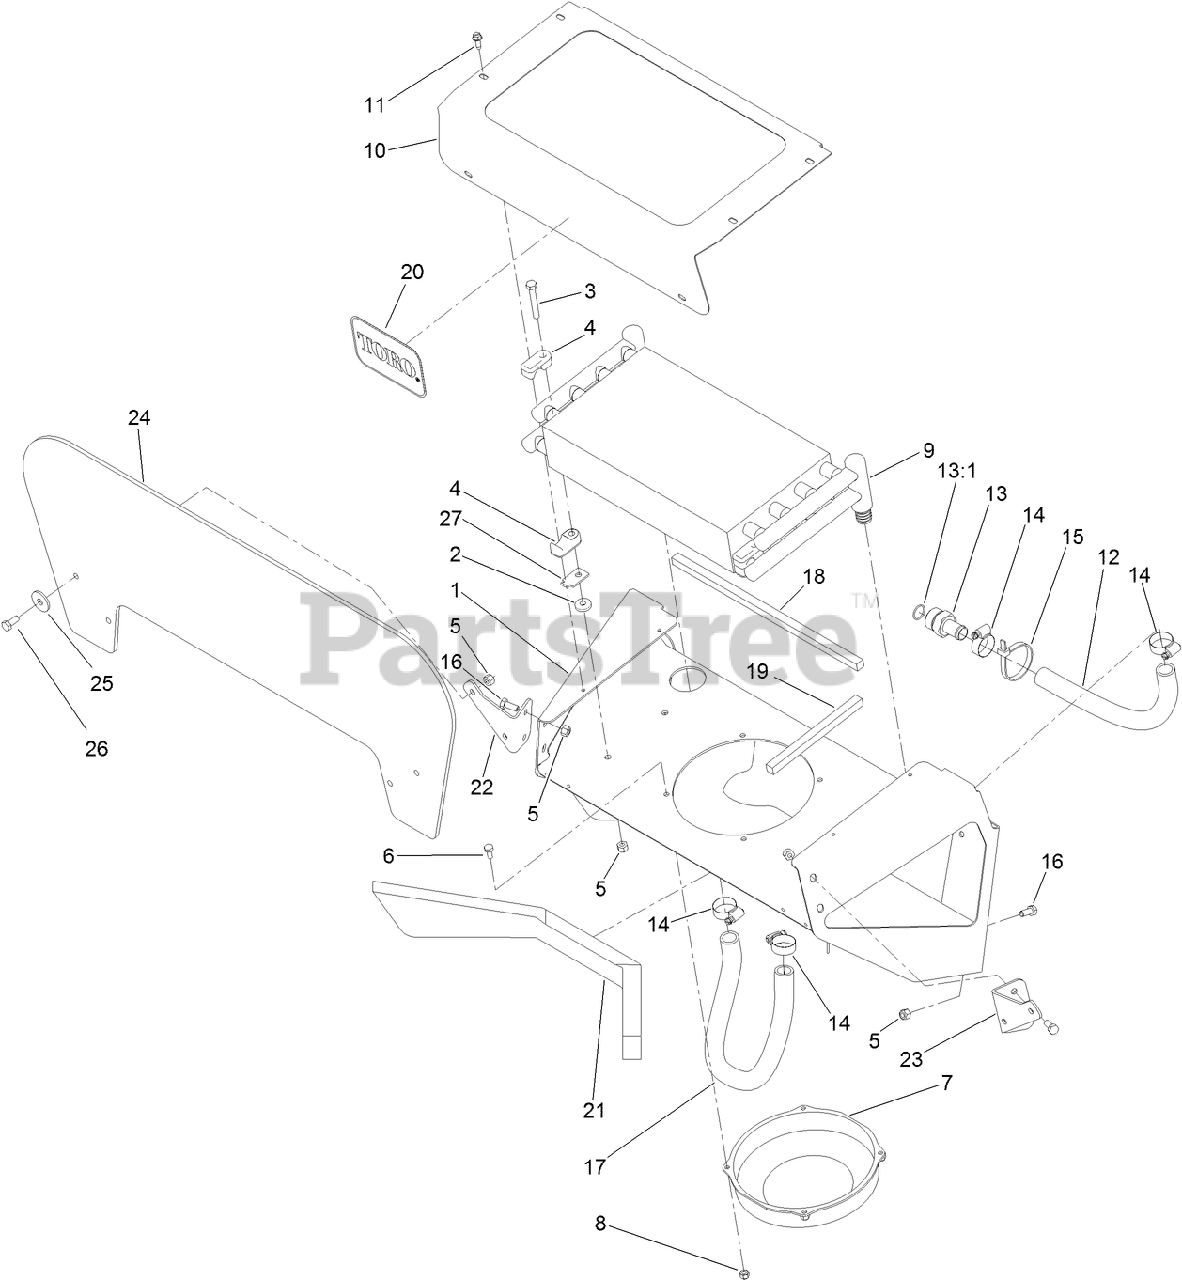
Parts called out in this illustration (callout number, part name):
1	MOUNT-COOLER
2	WASHER
3	SCREW-HH
5	NUT-LOCK, NI
6	SCREW-HH
8	NUT-LOCK, NI
9	COOLER-OIL
10	COVER-COOLER
11	SCREW-HWH
12	HOSE-HYD
13	FITTING-STRAIGHT
13:1	O-RING
14	CLAMP-HOSE
15	TIE-CABLE
16	SCREW-HH
17	HOSE-RETURN
18	FOAM-SEAL
19	FOAM-SEAL
21	SEAL-FOAM
22	BRACKET-SHIELD, RH
23	BRACKET-SHIELD, LH
24	SHIELD-CHIP
25	WASHER
26	SCREW-HH
27	PLATE-SUPPORT, CLAMP
